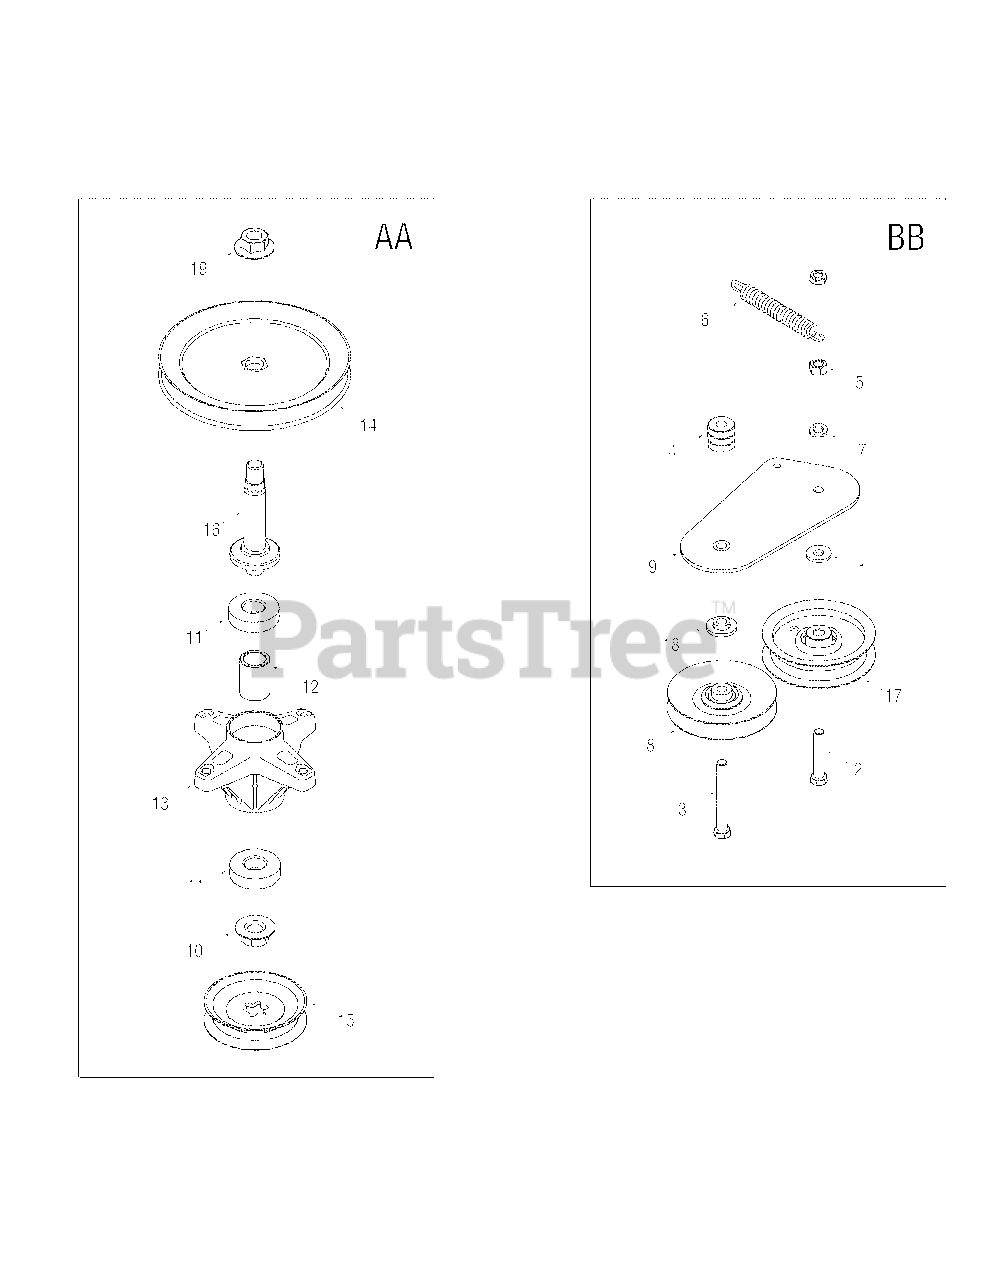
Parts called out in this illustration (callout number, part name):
1	Flat Washer, .38 x .93 x .11
2	Hex Cap Screw, 3/8-24 x 2
3	Hex Cap Screw, 3/8-16 x 3
5	Hex Nut, 3/8-24
6	Extension Spring, .620 x 5.62
7	Lock Washer, 3/8
8	Idler pulley, 4" Diameter
10	Flange Nut 5/8-18
11	Ball Bearing
13	Deck Spindle Housing
14	Deck Pulley 7"
15	Pulley 3.75"
16	Spindle Shaft
17	Idler Pulley 3.50 dia.
18	Shoulder Spacer, .625 x .169
19	Flange Nut 5/8-18
